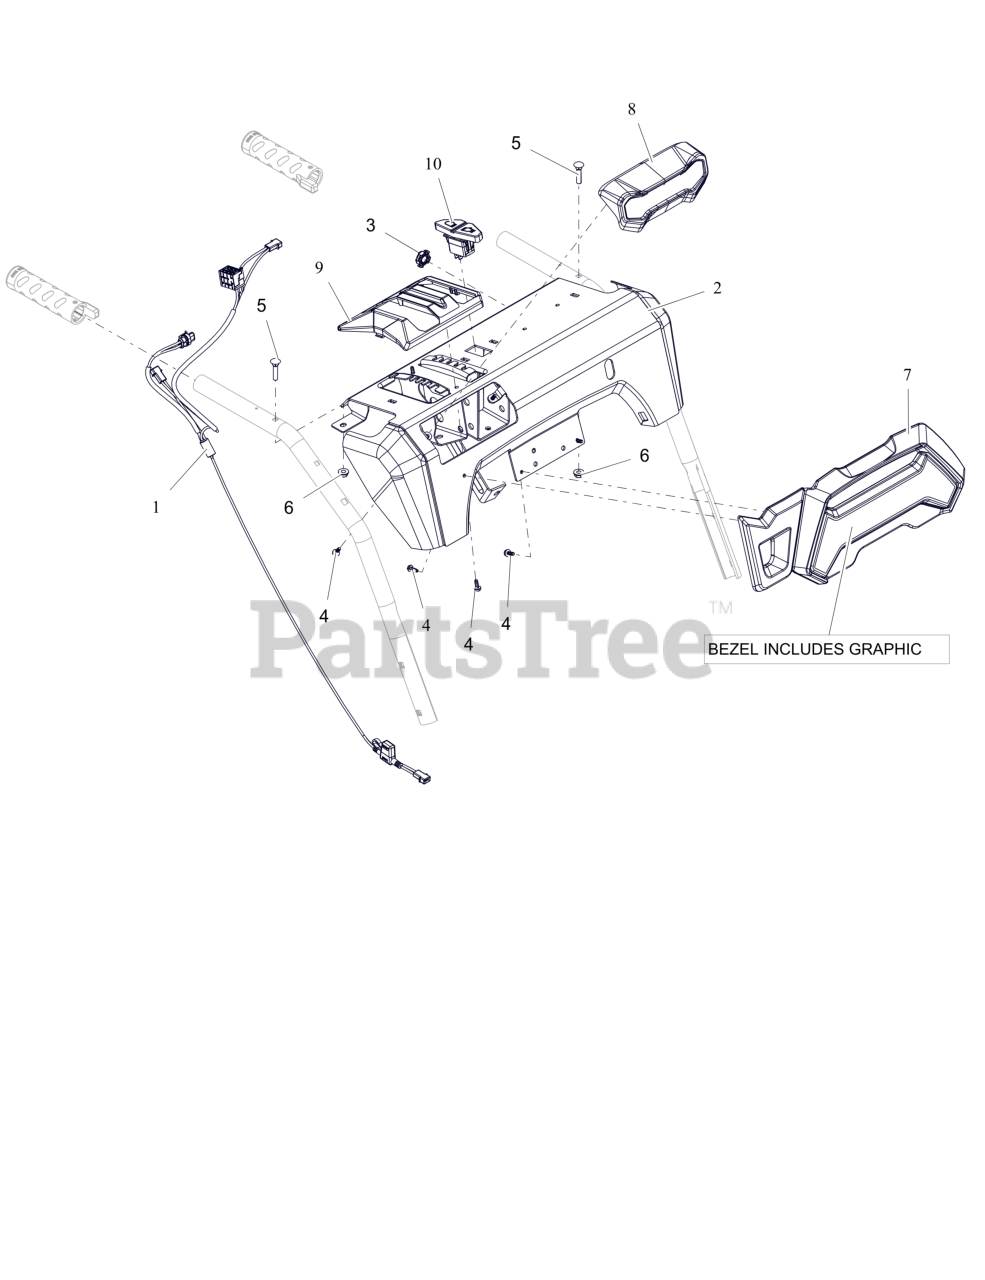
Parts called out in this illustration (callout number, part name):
1	HARNESS- WIRE - LT HG
2	PANEL, DASH-W/DECAL FRIC-ID
3	CRANK BUSHING, NYLON CHUTE BK
4	SCR, PLASTIC #10X.50
5	BLT-RDHDXLSQNK.25-20X1.25 G5ZC
6	NUT-LK-CTR-FLG .25-20 ZC120
7	BEZEL, LARGE - DELUXE
8	HEADLIGHT ASM- LED
9	BEZEL, SHIFT - FRICTION
10	SWITCH- ROCKER SPST-ON/OFF
